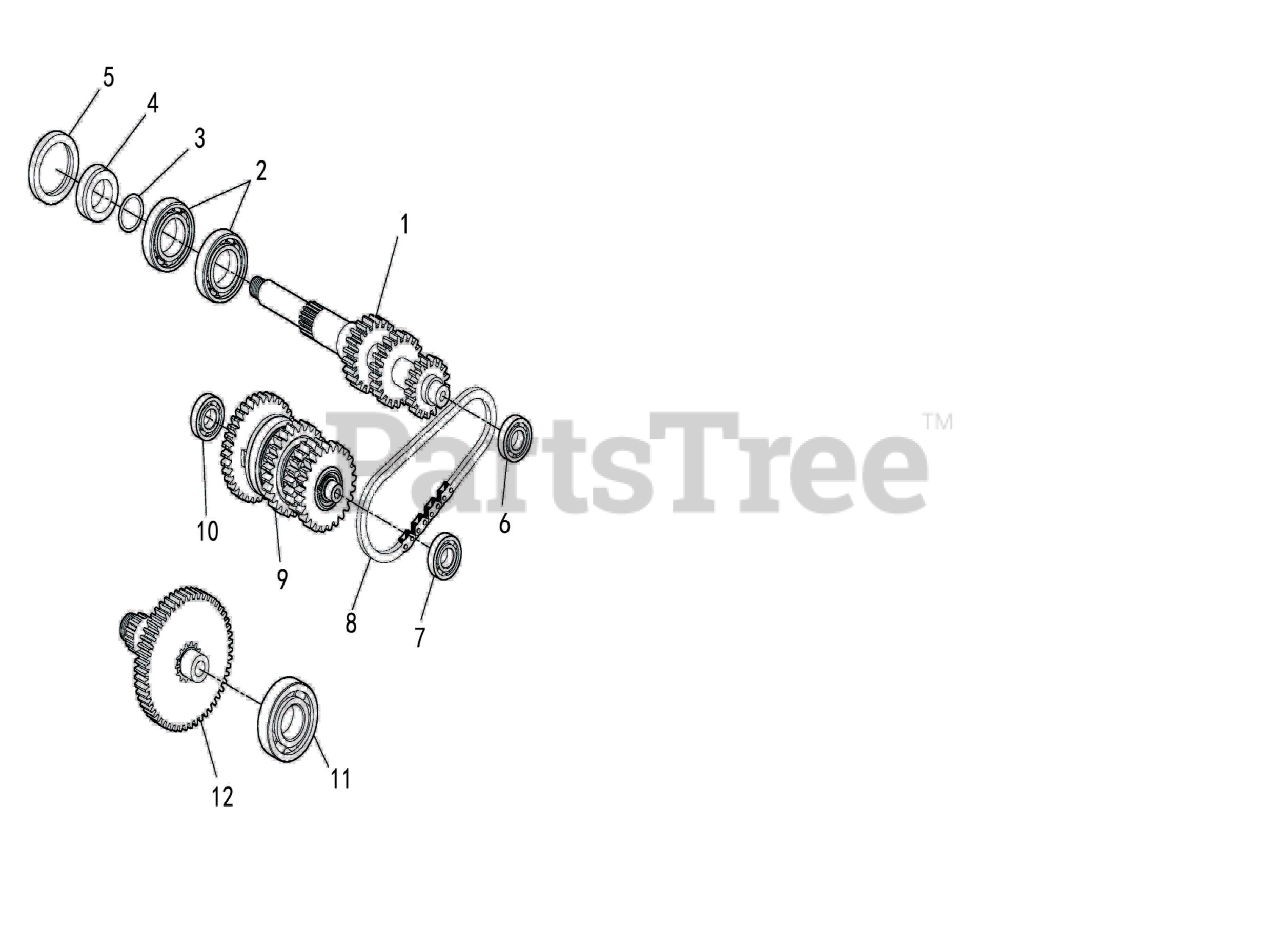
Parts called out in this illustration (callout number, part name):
1	Transmission Main Shaft
2	Bearing 6006C3
3	O-Ring 26.1X2.4
4	Secondary CVT Bushing
5	Oil Seal 42X55X8
6	Bearing 6203
7	Bearing 6202
8	tooth shaped chains for R gear
9	COUNTER SHAFT ASSEMBLY
10	Bearing 6203DLA8
11	Bearing 6303
12	X Driveshaft assy
